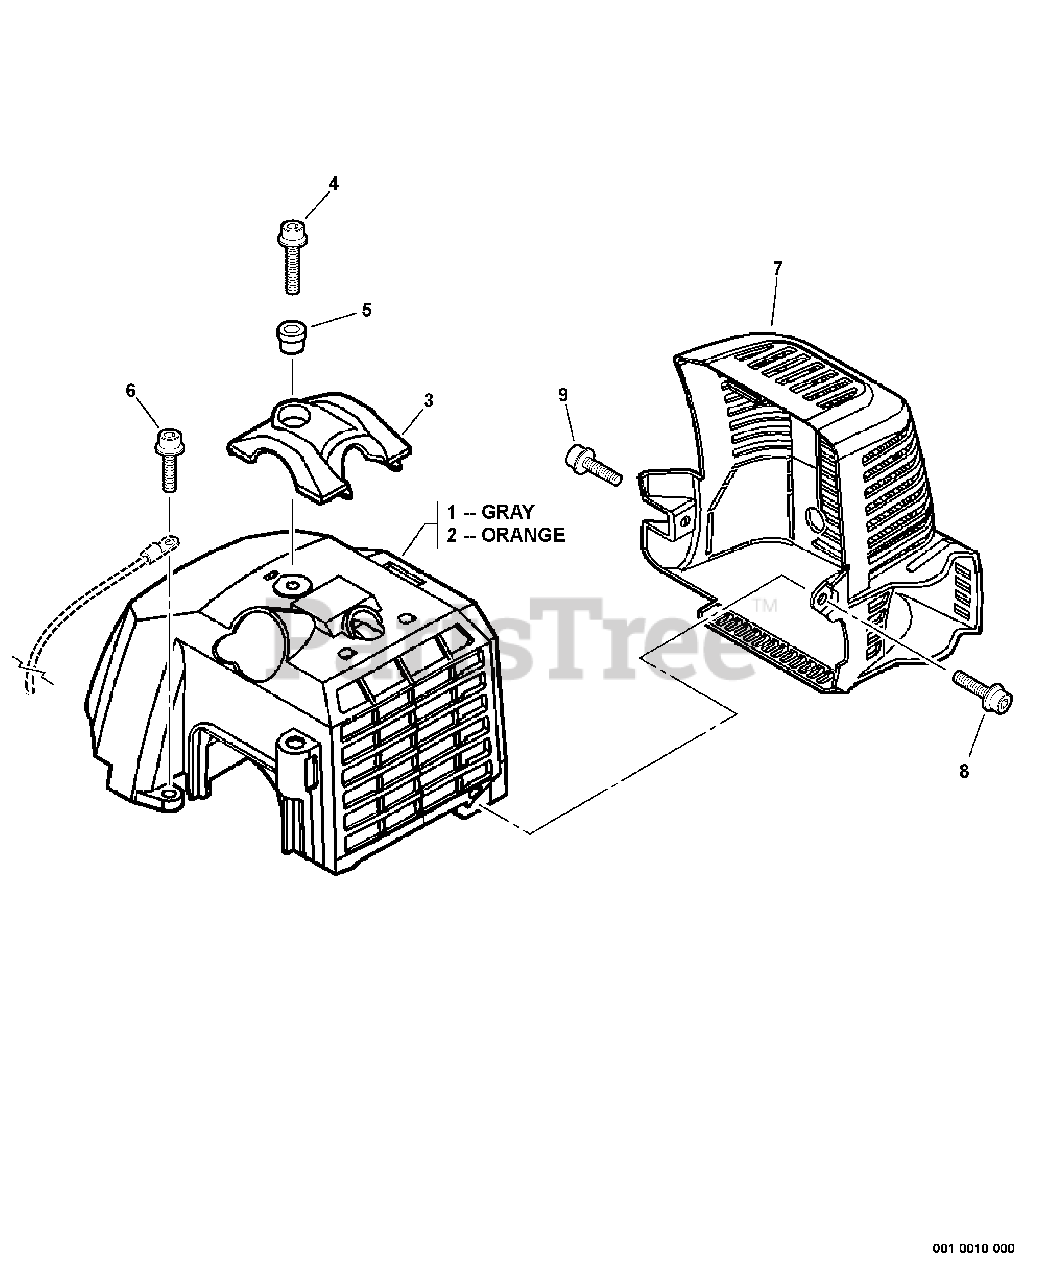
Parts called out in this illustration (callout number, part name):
1	COVER, ENGINE - GRAY
2	COVER, ENGINE - ORANGE
3	GUARD - TOP
4	SCREW - 5X20
5	COLLAR - 5
6	SCREW - 5X12
7	COVER, EXHAUST
8	SCREW - 5X20
9	SCREW - 5X12
